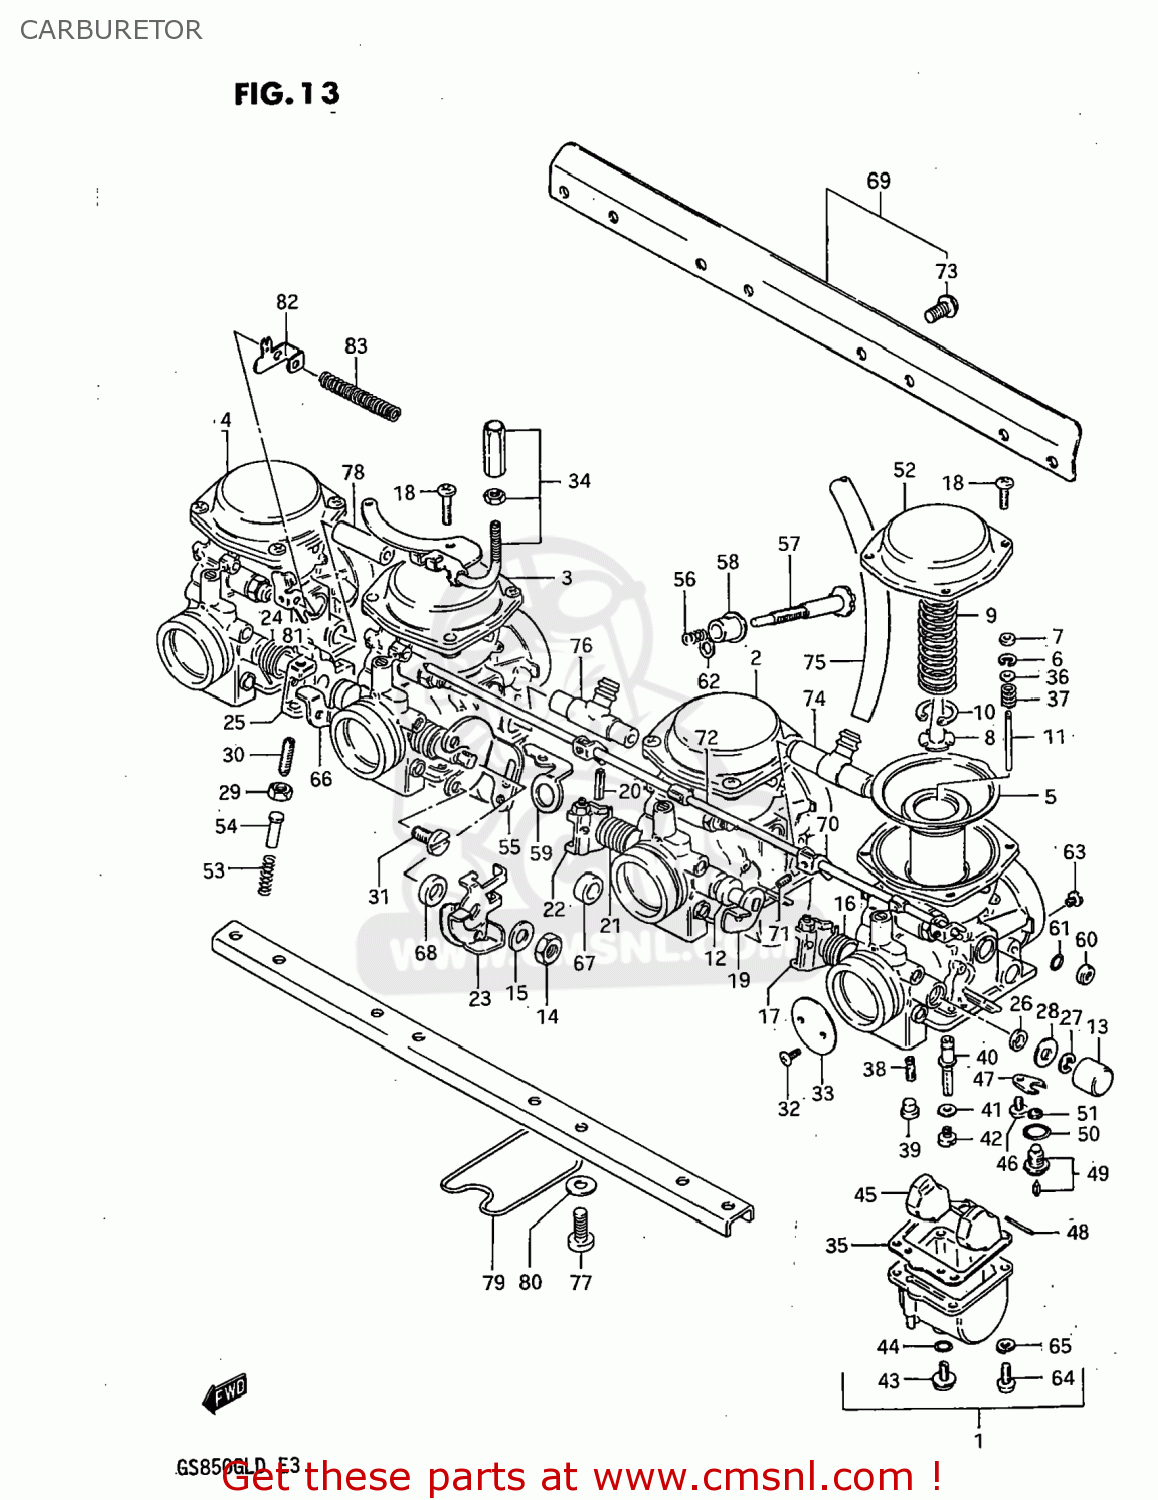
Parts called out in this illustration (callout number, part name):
1	CARBURETOR ASSEMBLY
2	CARBURETOR ASSEMBLY NO.2 (A
3	CARBURETOR ASSEMBLY,MIDDLE,RIGHT
4	CARBURETOR ASSEMBLY
5	DIAPHRAGM
6	CLIP,NEEDLE
7	RING
8	HOLDER,GUIDE
9	SPRING
10	E RING
11	NEEDLE JET
12	GASKET,THROTTLE SHAFT (NAS)
13	CAP
14	NUT 8MM
15	WASHER
16	SPRING,THROTTLE SHAFT
17	SHAFT,THROTTLE
18	SCREW
19	SHAFT ASSEMBLY
20	PIN,THROTTLE SHAFT
21	SPRING,THROTTLE SHAFT
22	LEVER,THROTTLE SHAFT
23	LEVER ASSEMBLY,THROTTLE
24	SPRING,THROTTLE SHAFT
25	SHAFT,THROTTLE
26	SEAL
27	E RING
28	GASKET,THROTTLE SHAFT (NAS)
29	NUT
30	SCREW
31	SCREW
32	SCREW
33	VALVE,THROTTLE
34	BRACKET,THROTTLE CABLE
35	GASKET,FLOAT CHAMBER (NAS)
36	WASHER
37	SPRING
38	JET,PILOT
39	PLUG,NEEDLE JET
40	JET,NEEDLE
41	WASHER,NEEDLE NOZZLE
42	JET,MAIN(115)
43	PLUG,DRAIN
44	GASKET (NAS)
45	FLOAT
46	SCREW 4X6
47	PLATE,NEEDLE VALVE FITING
48	PIN,FLOAT
49	VALVE ASSEMBLY,NEEDLE
50	O-RING,NEEDLE VALVE
51	FILTER
52	COVER,DIAPHRAGM
53	SPRING,THROTTLE SCREW
54	PIN,THROTTLE LEVER
55	BRACKET,THROTTLE ADJUST
56	SPRING
57	SCREW
58	BUSH
59	BRACKET,THROTTLE ADJUST
60	CAP,STARTER VALVE
61	O RING
62	WASHER
63	JET
64	SCREW
65	LOCK WASHER
66	SHAFT ASSEMBLY
67	RING
68	RING
69	CARBURETOR ASSEMBLY
70	LEVER
71	SCREW
72	SHAFT,STARTER
73	SCREW
74	NIPPLE
75	HOSE,CARBURETOR
76	NIPPLE
77	SCREW 6X12
78	NIPPLE
79	CLAMP
80	WASHER
81	LEVER,CHOKE CABLE
82	PLATE,CHOKE CABLE
83	SPRING,CHOKE CABLE
